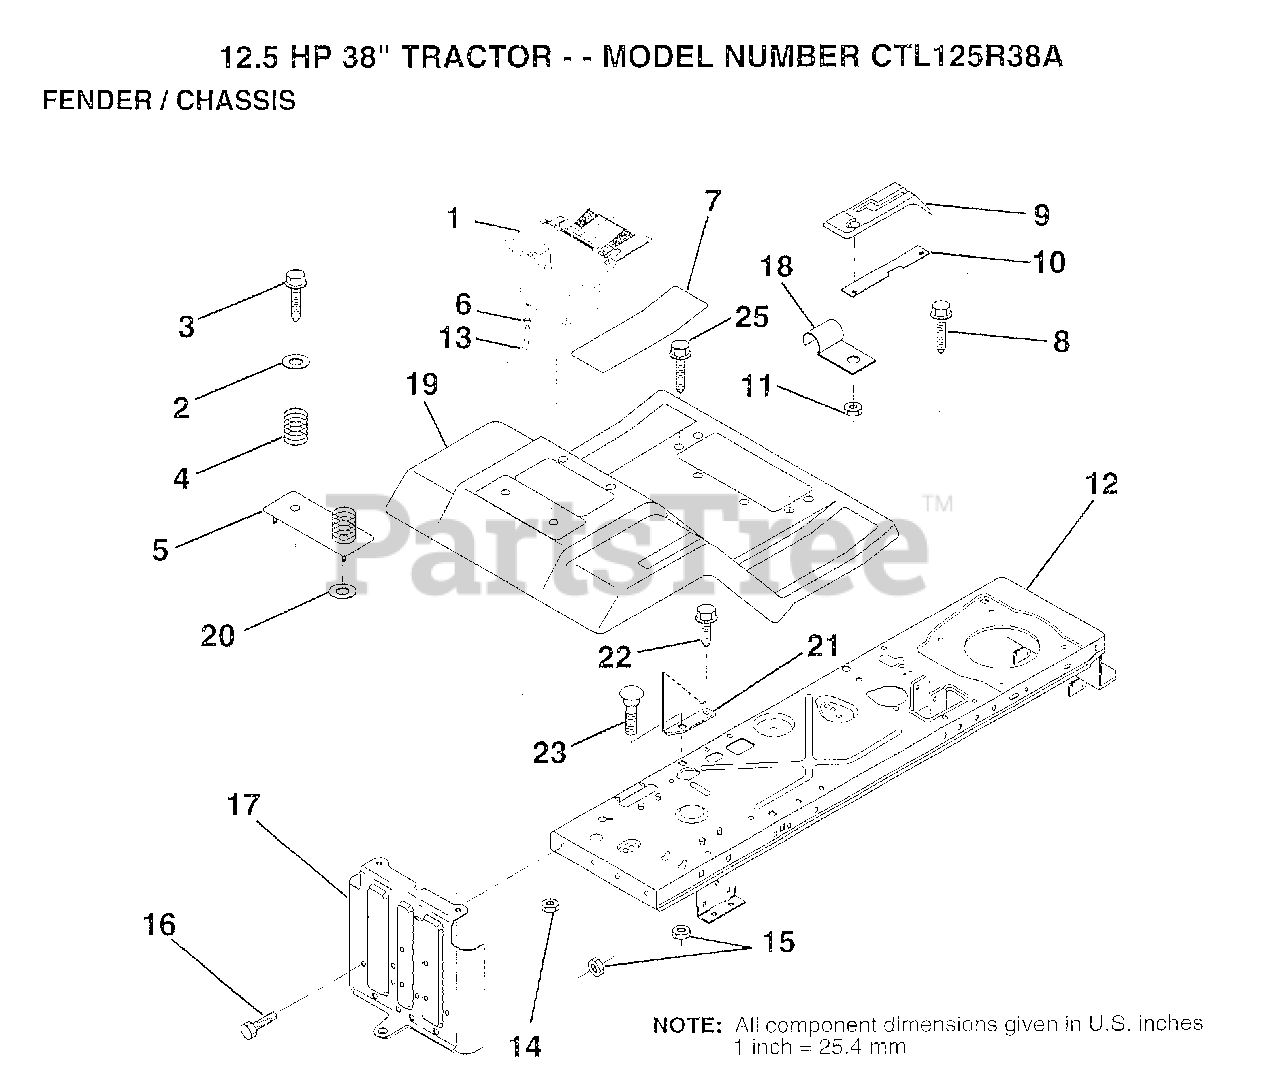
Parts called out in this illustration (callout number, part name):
2	WASHER
3	SCREW
4	SPRING COMPRESSIO
5	"PLATE, BATTERY"
6	HOSE CLAMP T
7	PAD FOOTREST
8	SCREW
10	"SHIFT LOCK, BAR"
11	NUT
13	TUBE T
14	NUT
16	BOLT
17	DRAWBAR
18	"CLIP,INSULATOR"
22	SCREW LT
25	SCREW TI
